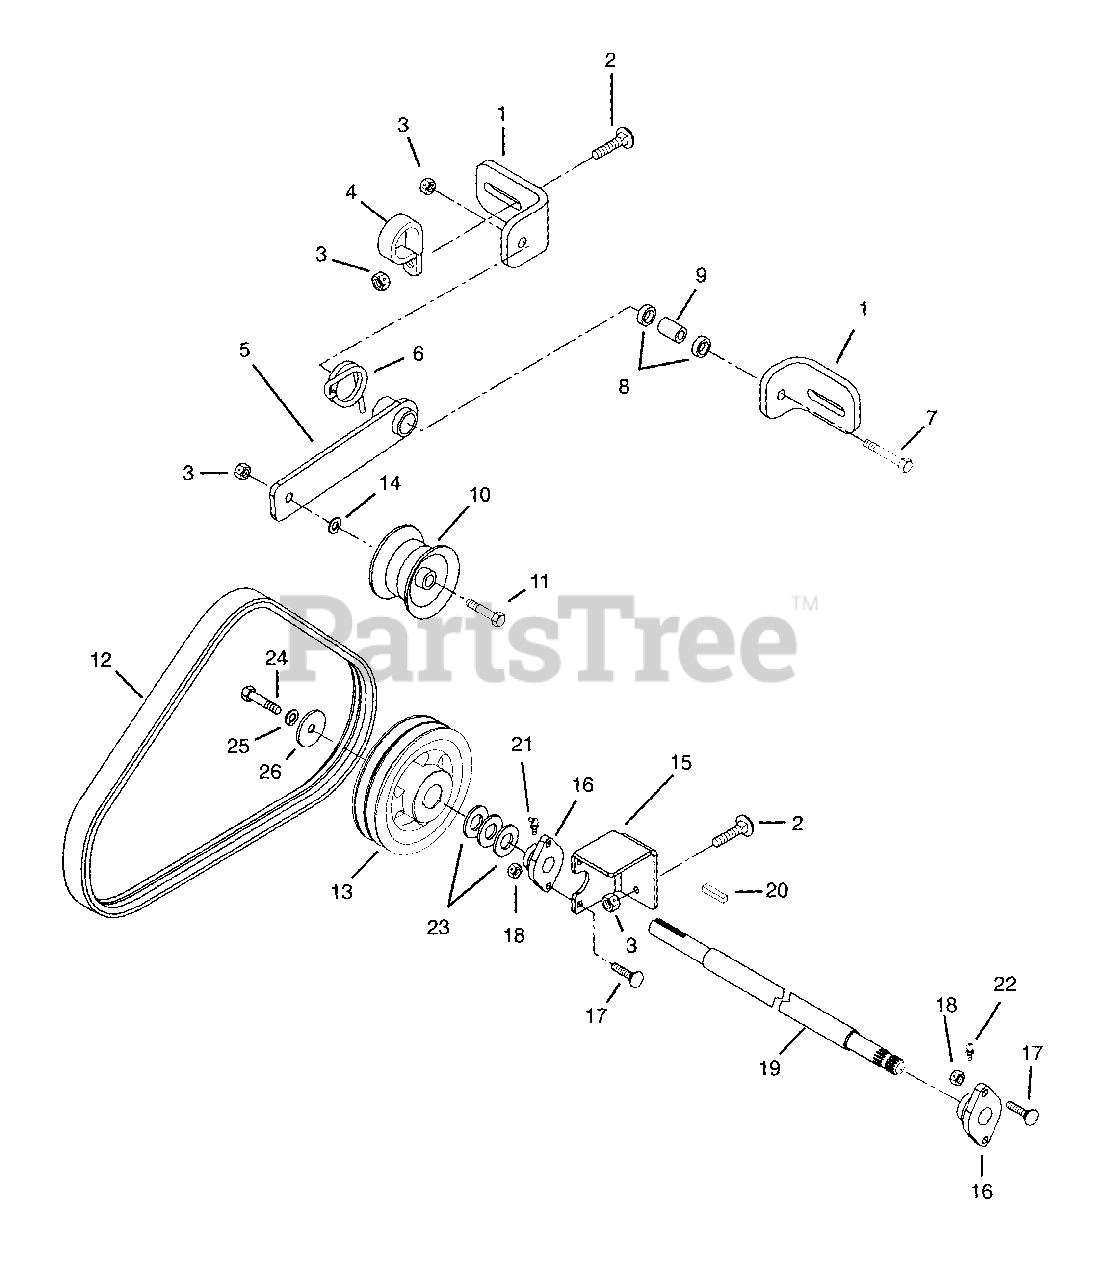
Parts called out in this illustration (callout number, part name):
1	Bracket, Idler
2	Bolt-Round Head Square Neck .38-16 x 1.00
3	Nut-Locking-Center .38-16
4	C-Clamp - .50 ID
5	Weldment, Idler Arm
6	Spring-Torsion
7	Bolt-Hex .38-16 x 2.50 Grade 5
8	Bushing-Bearing .75 ID x .88 x .50
9	Spacer .38 x .75 x 1.5
10	Flat Idler 2.75 x 1.25
11	Bolt-Hex .381-6 x 2.25 Grade 5
12	Belt, PTO
13	PTO Pulley
14	Washer-Flat-Steel .390 x .88 x .18
15	Weldment, Support Bracket
16	Bearing, Flanged with Set Screw
17	Bolt-Round Head Square Neck .31-18 x 1.25 Grade 5
18	Nut-Locking-Center .31-18
19	Weldment, PTO Shaft
20	Key-Square .25 x 1.25 x .25
21	45° Lube Fitting
22	Fitting-Lube .25-28 x .256
23	Washer-Hardened-Thrust 1.00 x 1.55 x .03
24	Bolt-Hex .25-20 x .75 Grade 5
25	Washer-Locking .44 x .109
26	Washer-Flat-Steel .469 x 2.00 x .25
